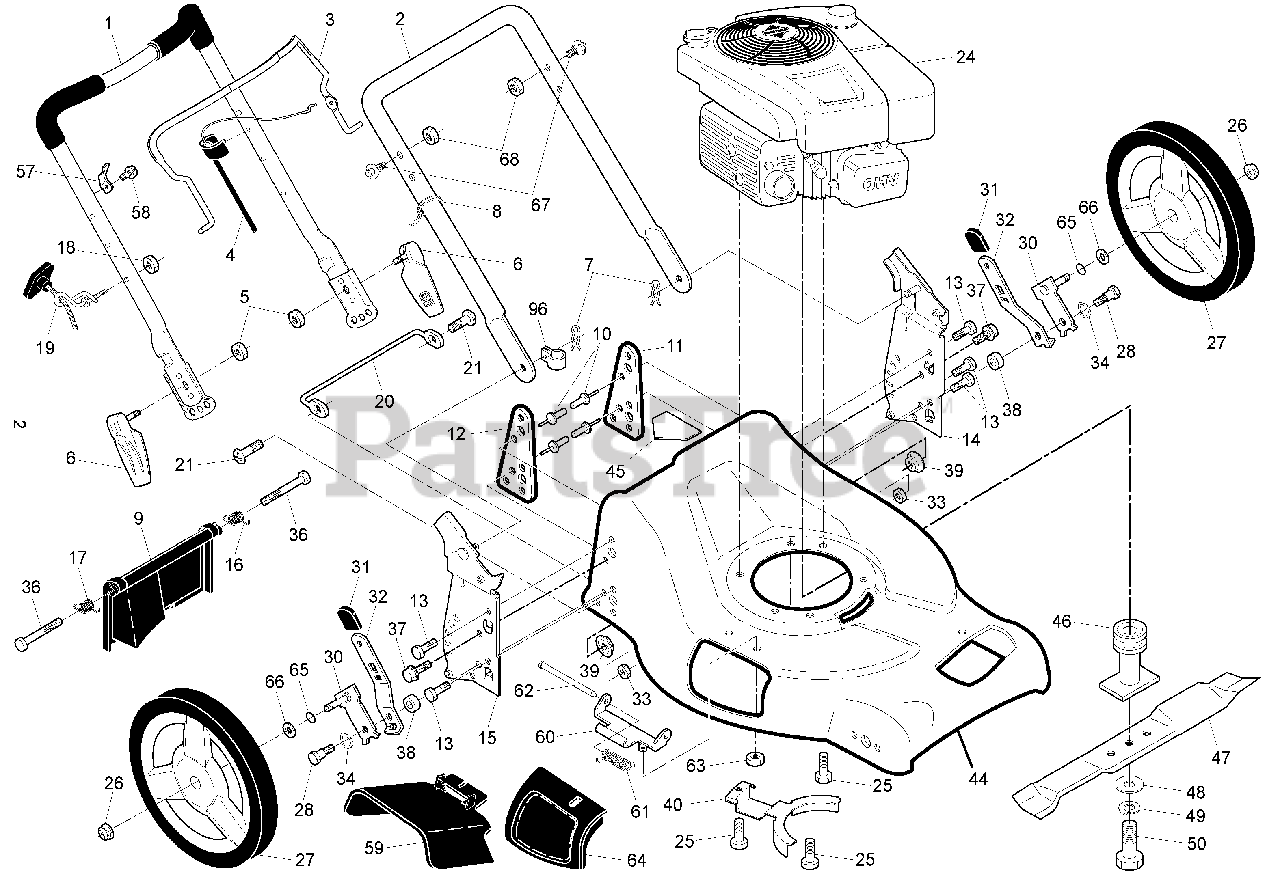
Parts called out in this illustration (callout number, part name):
1	Upper Handle
2	Lower Handle
3	Control Bar
4	Engine Zone Control Cable
5	Locknut, Hex 1/4-20
6	Handle Knob Assembly, Quick-Release
7	Hairpin Cotter
8	Wire Tie
9	Rear Door Assembly
11	Support Bracket, LH
12	Support Bracket, RH
13	Screw 1/4-20 x 5/8
14	Handle Bracket Assembly, LH
15	Handle Bracket Assembly, RH
16	Spring, Rear Door, LH
17	Spring, Rear Door, RH
18	Locknut, Hex 1/4-20
19	Rope Guide
20	Foot Guard, C.E.
21	Screw, Self-Tapping, Hex Head 1/4-20 x 1/2
25	Hex Head Thread Rolling Screw 3/8-16 x 1-1/8
26	Hex Flange Nut
27	Wheel & Tire Assembly, Rear, 12"
28	Shoulder Bolt 5/16-18 x .33
30	Axle Arm Assembly, Rear
31	Selector Knob
32	Selector Spring
33	Nut, Hex 5/16-18
34	Washer, Curved, Cylindrical
37	Thread Cutting Screw w/Sems 5/16-18 x 3/4
39	Nut, Hex, Flanged 5/16-18
40	Belt Keeper
44	Lawn Mower Housing
45	Danger Decal
46	Blade Adapter / Pulley
48	Hardened Washer
49	Helical Washer 3/8-24 x 1-3/8 Grade 8
50	Hex Head Machine Screw 3/8-24 x 1-3/8 Grade 8
57	Upstop Bracket
59	Discharge Deflector
60	Hinge Bracket Assembly
61	Spring, Hinge
62	Rod, Hinge
63	Locknut, Hex 1/4-20
64	Mulcher Door
66	Washer, Flat
68	Nut, Hex 1/4-20
96	Clip, Cable
